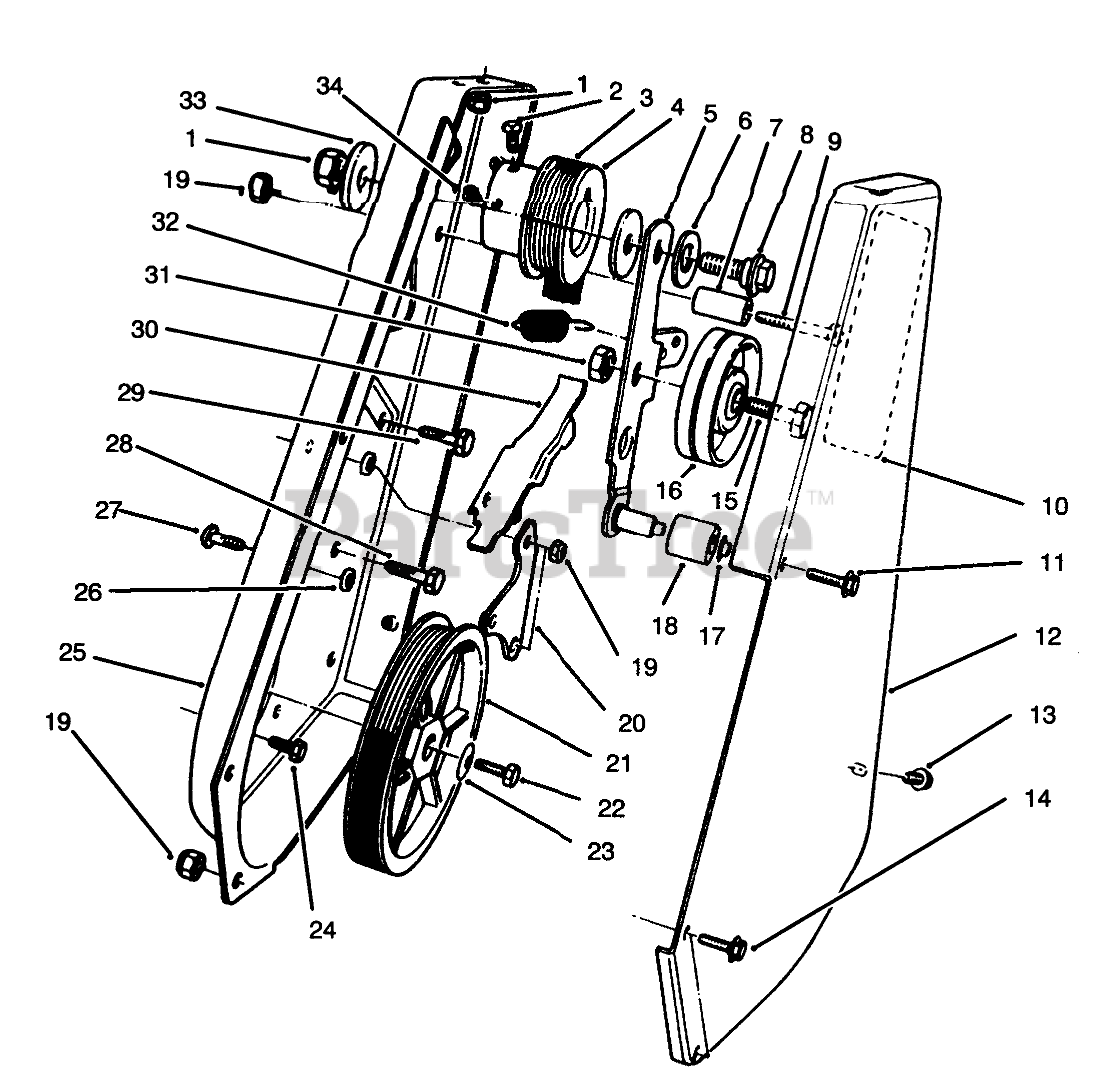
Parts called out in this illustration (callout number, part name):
1	NUT-LOCK, NI
2	SCREW-SQH
3	BELT - DRIVE
4	ENGINE PULLEY
5	Idler Arm Assembly (Incl. Ref. #17 & 18)
6	WASHER
7	SLEEVE-GUIDE, BELT
8	SCREW-SHOULDER
9	SCREW-HH
10	DECAL
11	SCREW-HWH, TAP
12	Cover-Drive
13	SCREW
14	SCREW-HWH
15	SCREW-HH
16	PULLEY-IDLER
17	NUT-PUSH
18	ROLLER-BRAKE
19	NUT-LOCK, NI
20	PIVOT PLATE ASM
21	ROTOR PULLEY ASY
22	SCREW-HH
23	WASHER-BELLEVILLE
24	SCREW-SHH
25	Sideplate-LH
26	SPACER-PLATE, PIVOT
27	SCREW-HSBH
28	SCREW-HH
29	SCREW-HH
30	BRAKE-ARM
31	NUT-LOCK, CONE
32	SPRING-EXTENSION
33	WASHER-PIVOT
34	SCREW-HSH
